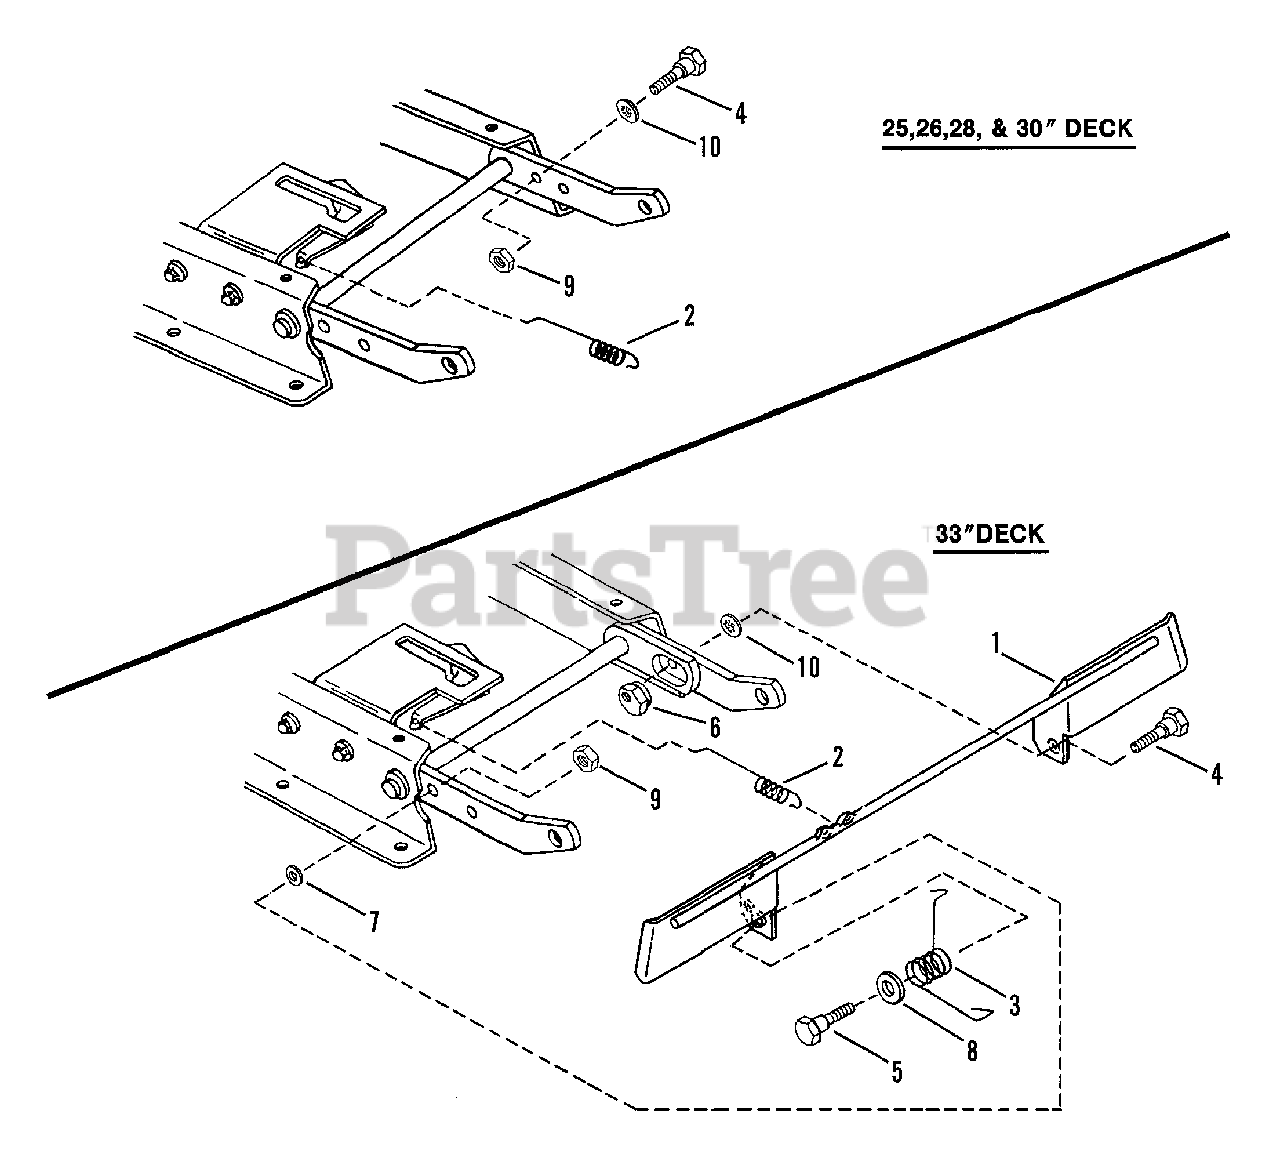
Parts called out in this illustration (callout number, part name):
1	PEDAL, Blade Stop Control (25,26,28,30, & 33" Models)
2	SPRING, Latching
3	SPRING, Pedal
4	BOLT, 3/8-24x3/4" Shoulder
5	BOLT, 3/8-24x9/16" Shoulder
6	ECCENTRIC, Leveling
7	WASHER, 3/8" Flat
8	WASHER, 1/2 Flat
9	NUT, 3/8-24 Hex Lock
10	WASHER, 3/8 Internal Tooth Lock
